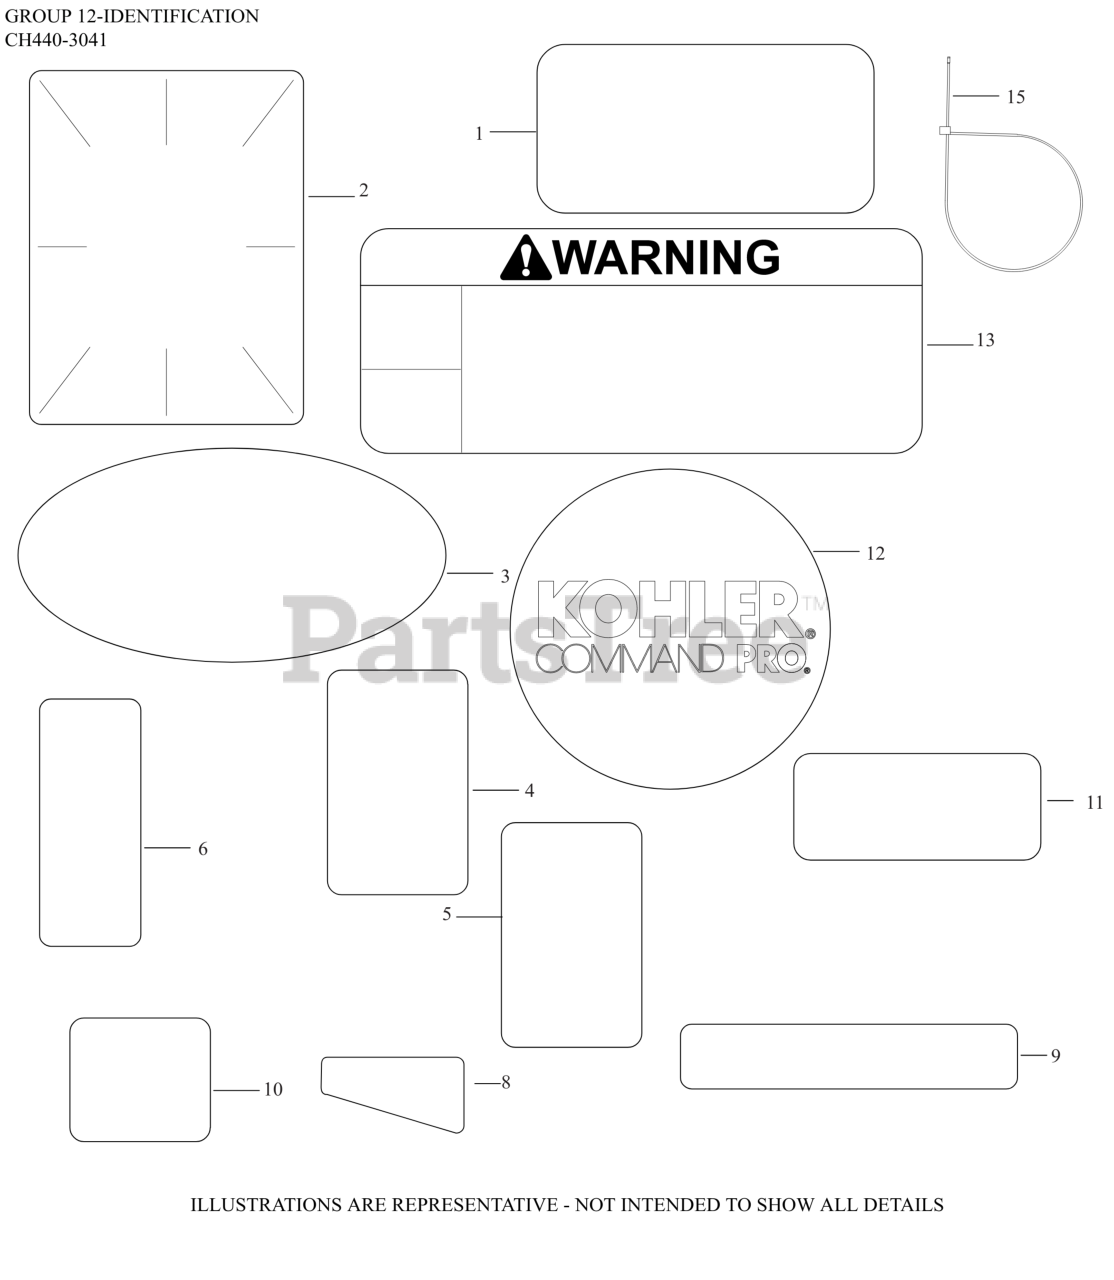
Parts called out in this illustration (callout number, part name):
1	LABEL, MAINTENANCE (CKY)
2	LABEL, CLEAR LAMINATION
3	DECAL, QUAD CLEAN SILVER
4	DECAL, SNOW FLAKE
5	DECAL, SUN
6	DECAL, FUEL/CHOKE - ON/OFF
8	DECAL, 14 HP/429cc/CH440
9	DECAL, THROTTLE
10	DECAL, BASE ARROW
11	LABEL, CANADIAN COMPLIANCE
11	DECAL, ETHANOL WARNING
12	LABEL, RECOIL 75MM
13	DECAL, WARNING
